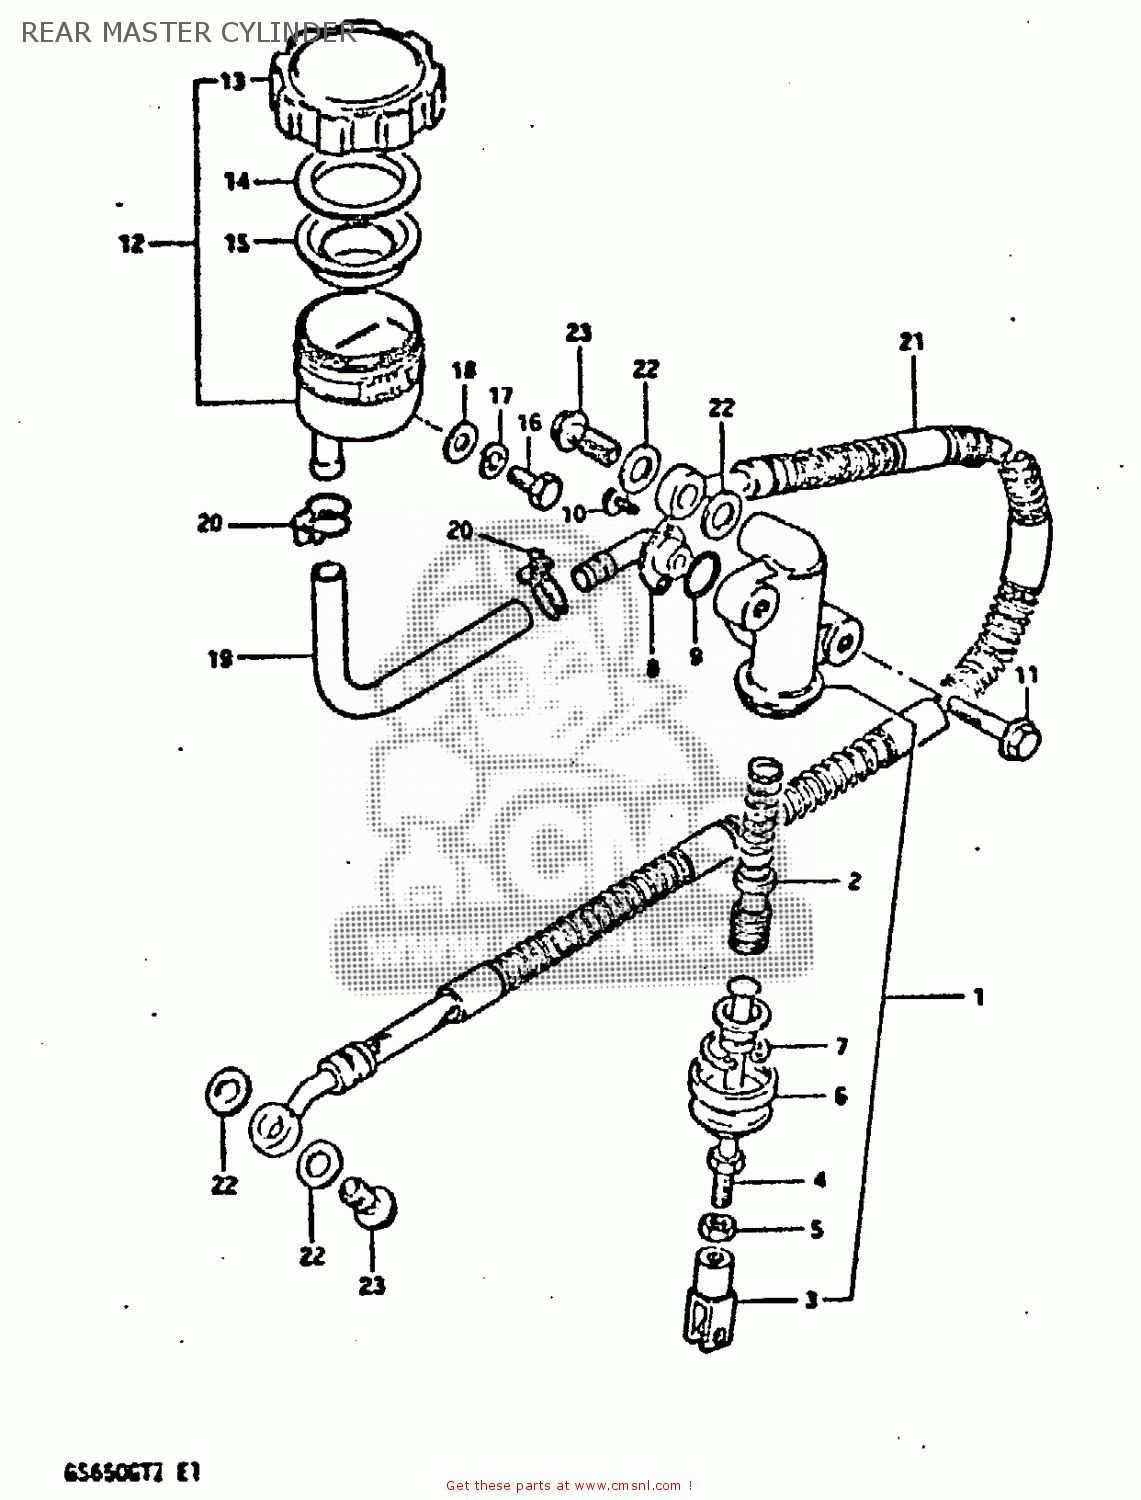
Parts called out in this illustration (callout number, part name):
1	CYLINDER ASSEMBLY,REAR MASTER
2	PISTON/CUP SET
3	YOKE
4	ROD,PUSH
5	NUT
6	BOOT
7	CIRCLIP
8	CONNECTOR,HOSE
9	O RING
10	SCREW
11	BOLT
12	TANK ASSEMBLY,RESERVOIR
13	CAP
14	PLATE,DIAPHRAGM
15	DIAPHRAGM
16	BOLT, UPPER
17	LOCK WASHER
18	WASHER
19	HOSE,RESERVOIR TANK
20	CLAMP
21	HOSE,REAR BRAKE
22	WASHER
23	BOLT,UNION
